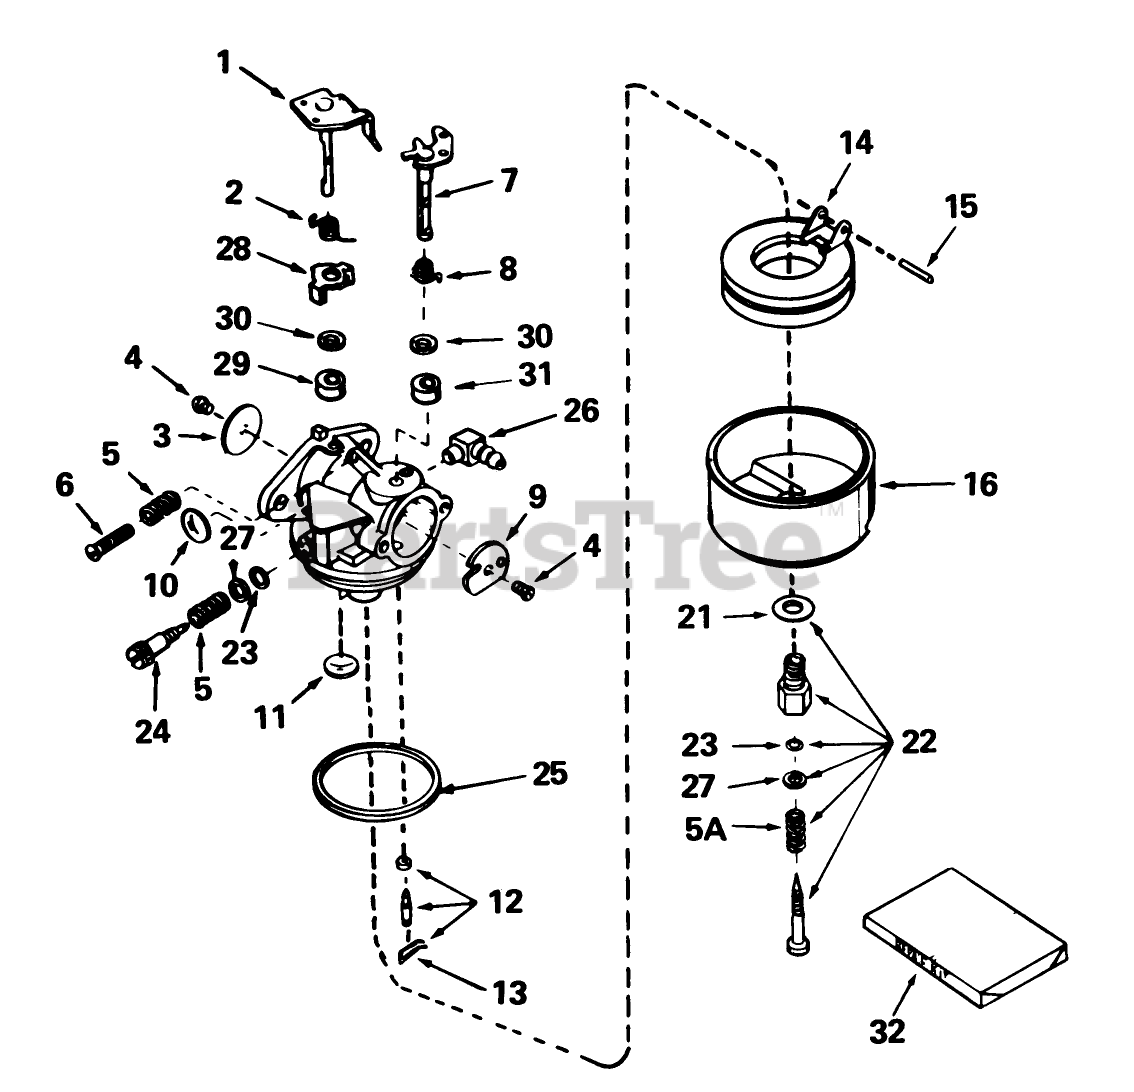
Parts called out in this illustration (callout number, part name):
1	Shaft/Lever-Throttle
2	Spring-Return, Throttle
3	Shutter-Throttle
4	Screw-Shutter
5	Spring-Tension
5A	Spring
6	Screw-Throttle Crack Screw / Idle Speed
7	Shaft Lever Assy., Choke
8	Spring, Choke Return
9	Choke Shutter
10	Plug-Welch, Idle Mixture Well
11	Plug-Welch, Atmospheric Vent
12	Inlet Needle, Seat Clip Assy. (Incl. No. 13)
13	Clip-Spring
14	Float
15	Shaft-Float
16	Bowl-Float (no drain)
21	Washer-Bowl Nut
22	Adjustment Screw Assembly, Main (Incl. Nos. 5A, 21, 23 27)
23	ORing
24	Screw Main Adjustment
25	O Ring-Bowl, Float
26	Fitting-Fuel
27	Washer
28	Retainer, Seal
29	Seal-Dust
30	Washer-Seal, Dust
31	Seal-Dust
32	Repair Kit
